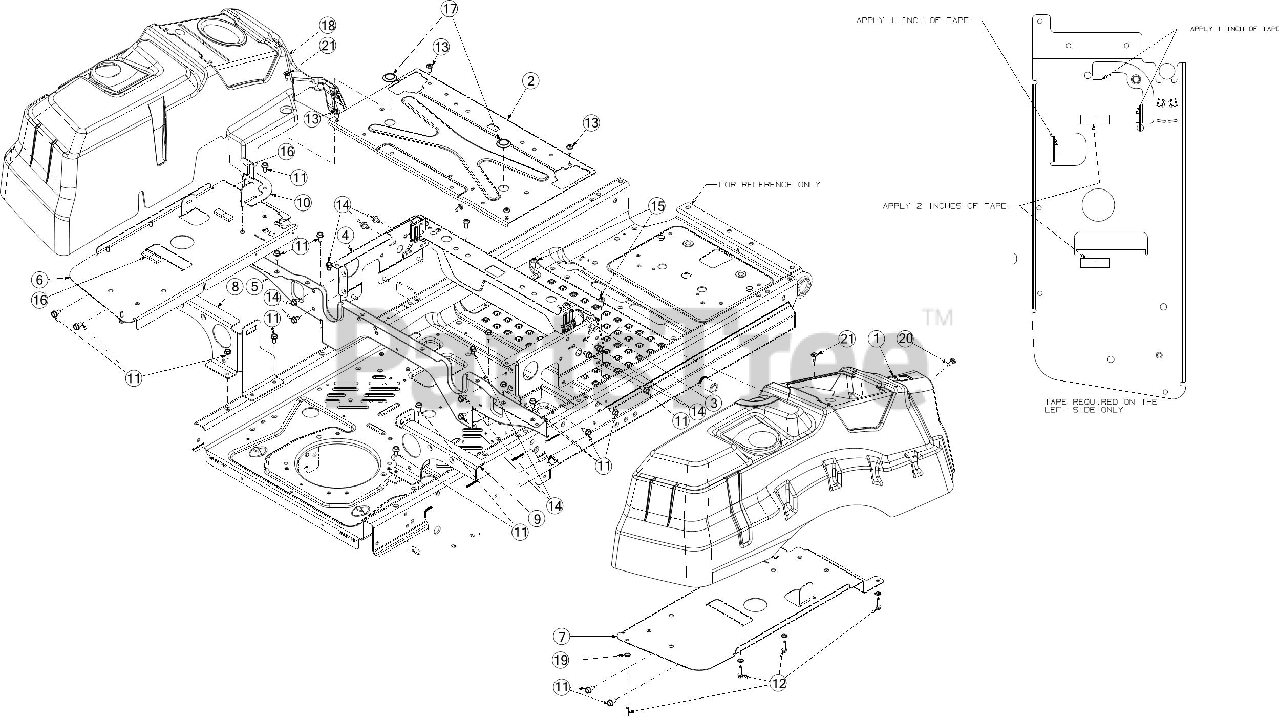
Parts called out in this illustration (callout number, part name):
1	CONSOLE ASSEMBLY (RH) (CAMO)
2	SEATBOX TOP PLATE
3	LAPBAR BRACE BRACKET
4	SEAT FRAME
5	REAR SEATBOX BRACE
6	TANK SUPPORT PLATE (LH)
7	TANK SUPPORT PLATE (RH)
8	REAR BRACKET SUPPORT (LH)
9	REAR BRACKET SUPPORT (RH)
10	REAR TANK BRACKET
11	SCREW 5/16-18 x .750
12	SCREW 5/16-14 x 1
13	SCREW 5/16-18 x .750
14	SCREW 5/16-18 x .500
15	SCREW 5/16-18 X.75
16	FOAM TAPE .625 WIDE x .25 THK BULK
18	CONSOLE ASSEMBLY (LH) (CAMO)
20	TORX SHOULDER SCREW 1/4-20
21	SHOULDER SCREW M6-1 .368 X.115
